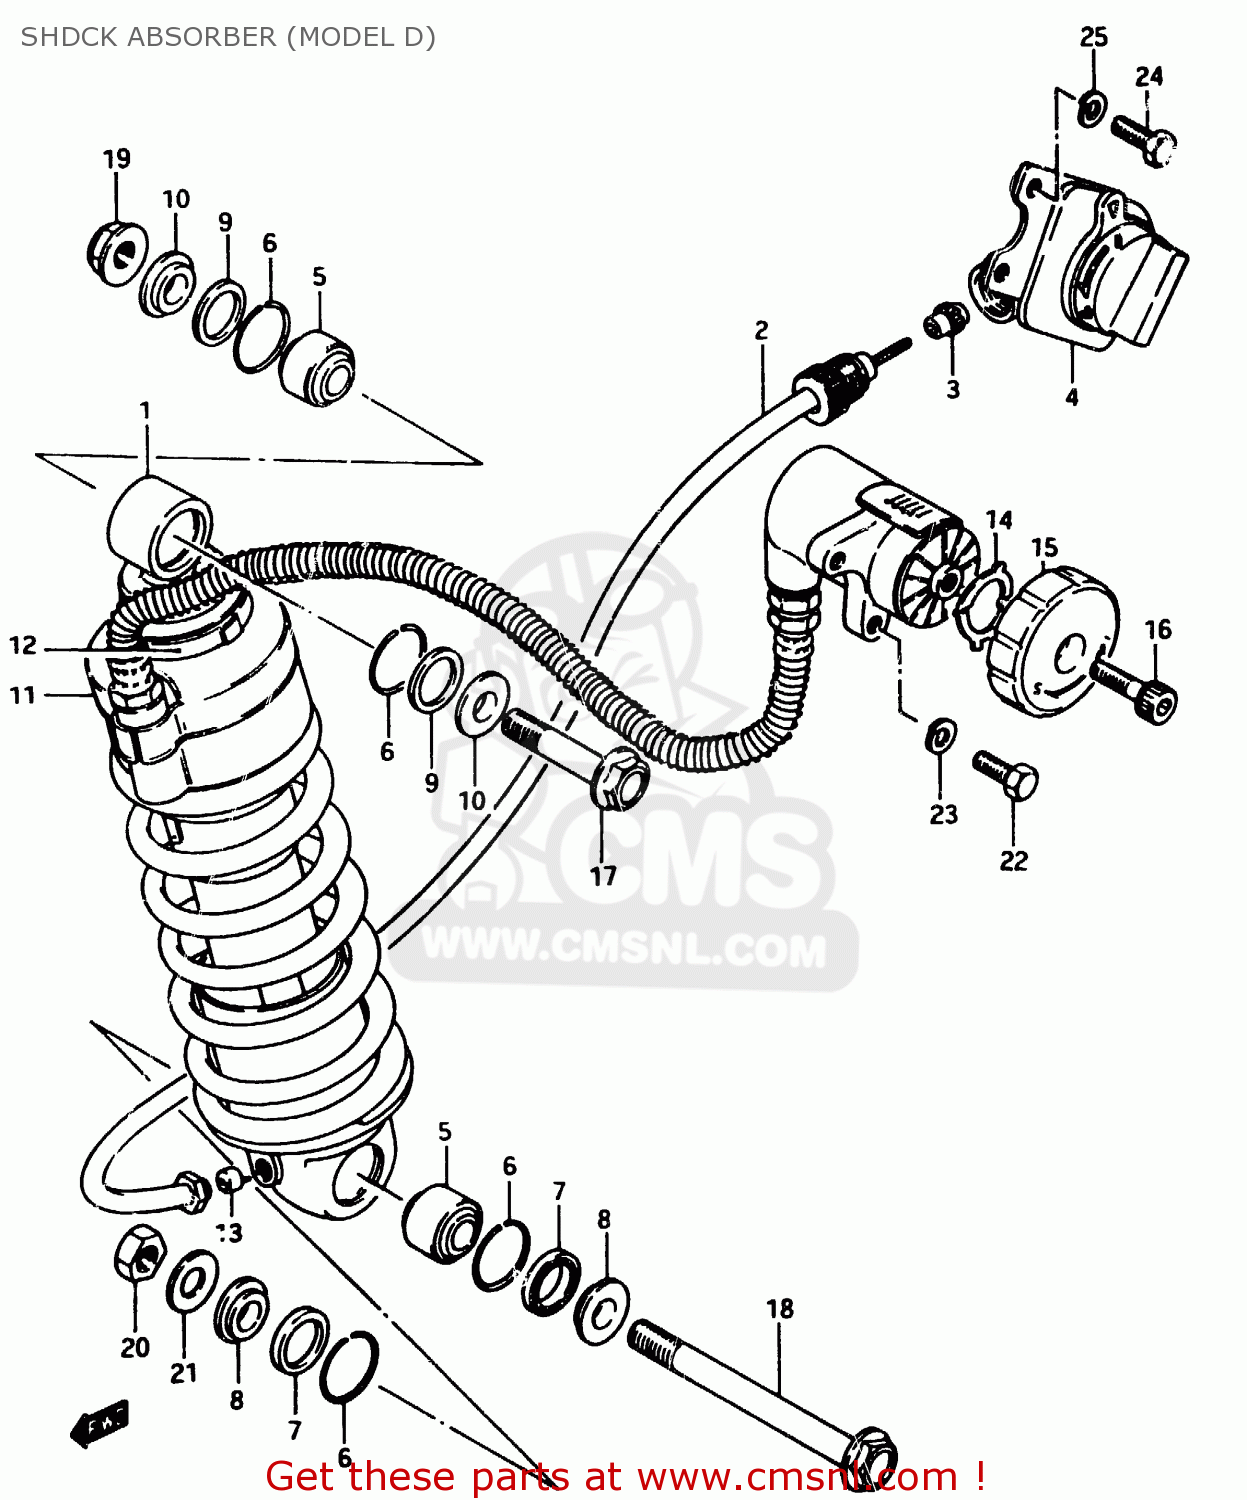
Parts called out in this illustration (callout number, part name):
1	SHOCK ABSORBER, REAR
2	CABLE,CONTROL
3	GEAR
4	ADJUSTER
5	BEARING
6	RING
7	DUST SEAL
8	SPACER
9	SEAL,DUST
10	COLLAR
11	COVER
12	BAND
13	CAM,DAMPER ADJUSTER
14	PLATE SET
15	LEVELING PLATE
16	BOLT
17	BOLT(10X50)
18	BOLT(10X115)
19	NUT
20	NUT
21	WASHER
22	BOLT 6X16
23	LOCK WASHER
24	BOLT 6X16
25	LOCK WASHER
